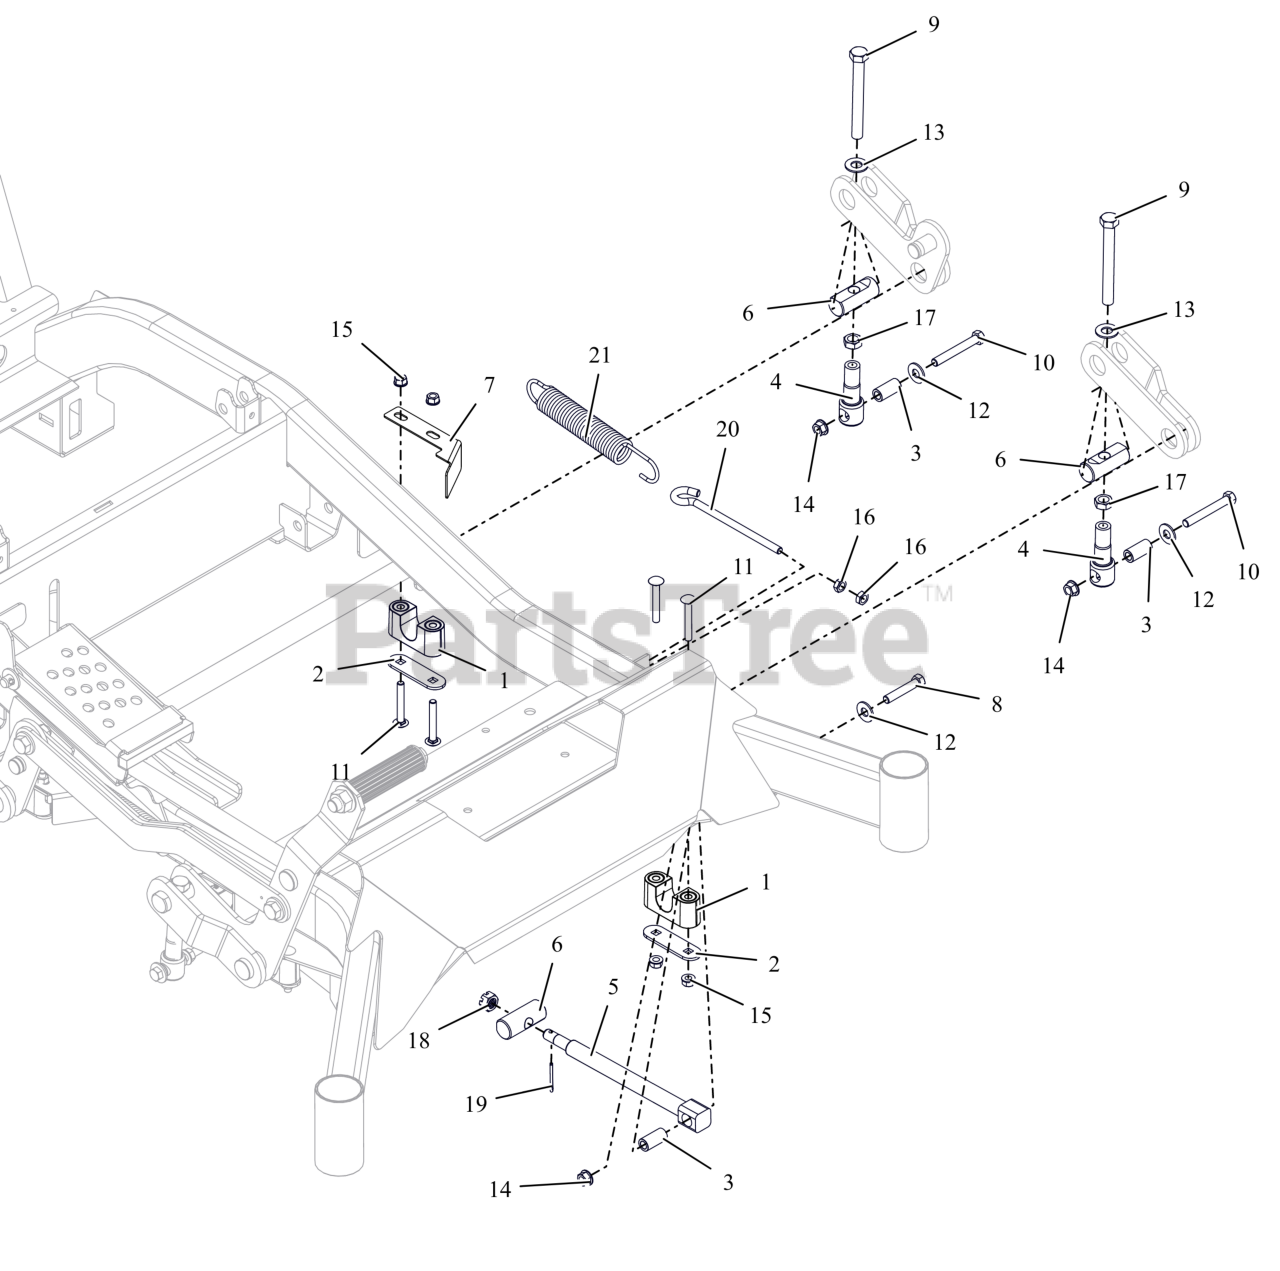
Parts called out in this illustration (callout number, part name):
1	ASM-BUSHING, DECK LIFT
2	PLATE, BEARING SUPPORT
3	SPACER, DECK LEVELING
4	LINK, DECK LIFT FORMED
5	DRAG,LINK-HD
6	PIN, DECK LIFT
7	GUARD, STOP CE 60 (BLACK)
8	BLT,HEX .38-16X2.00 G5 ZCC
9	BLT, HEX .50-13X4.50F G8 ZCC
10	BLT, HEX .38-16X2.75 G8 ZCC
11	BLT, RHSSN.31-18X2.25 G5 ZCC
12	WSHR,FLT .438X1.00X.083 ZCC
13	WSHR, FLT .557X1.040X.102 ZCC
14	NUT-LK-TOP-FLG .38-16 ZC120
15	NUT,LK-CTR-FLG .31-18 GF ZCC
16	NUT-JAM .375-16 G2 ZCC
17	NUT-JAM .500-13 G2 ZCC
18	NUT-SL .50-13
19	PIN,CTR.12X1.25EXTPRSQCT ZC120
20	BOLT,.38-16 X 5.25-.62 DIA EYE
21	SG-TENS .162X1.25X8.25 WLD 25
